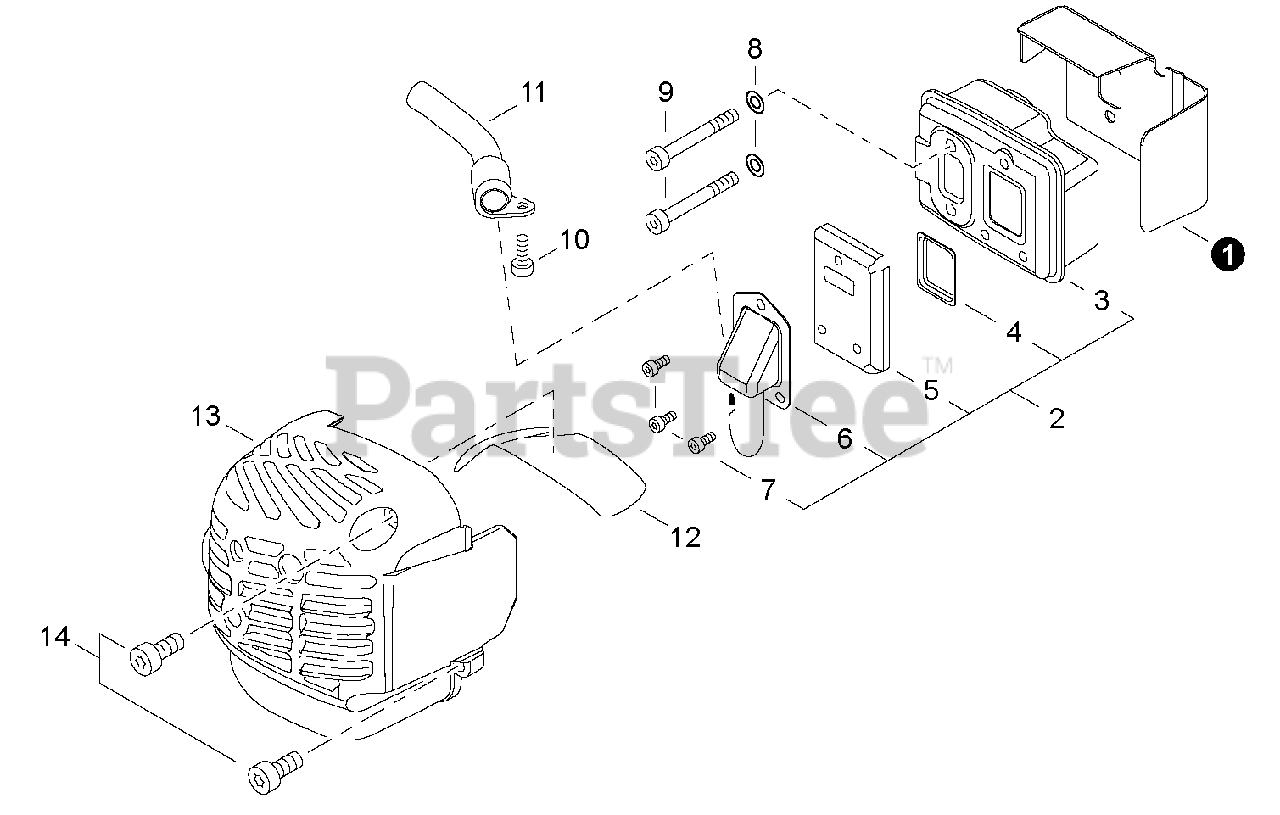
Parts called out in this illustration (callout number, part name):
1	HEAT SHIELD, EXHAUST
2	MUFFLER ASSY
3	MUFFLER
4	SCREEN, SPARK ARRESTER
5	GASKET, EXHAUST
6	GUIDE, EXHAUST
7	BOLT, TORX 4×8
8	WASHER 5.5×12×0.8
9	BOLT, TORX 5×55
10	BOLT, TORX 5×10
11	GUIDE, EXHAUST
12	PLATE, INSULATOR
13	COVER, MUFFLER
14	BOLT, TORX 5×16
